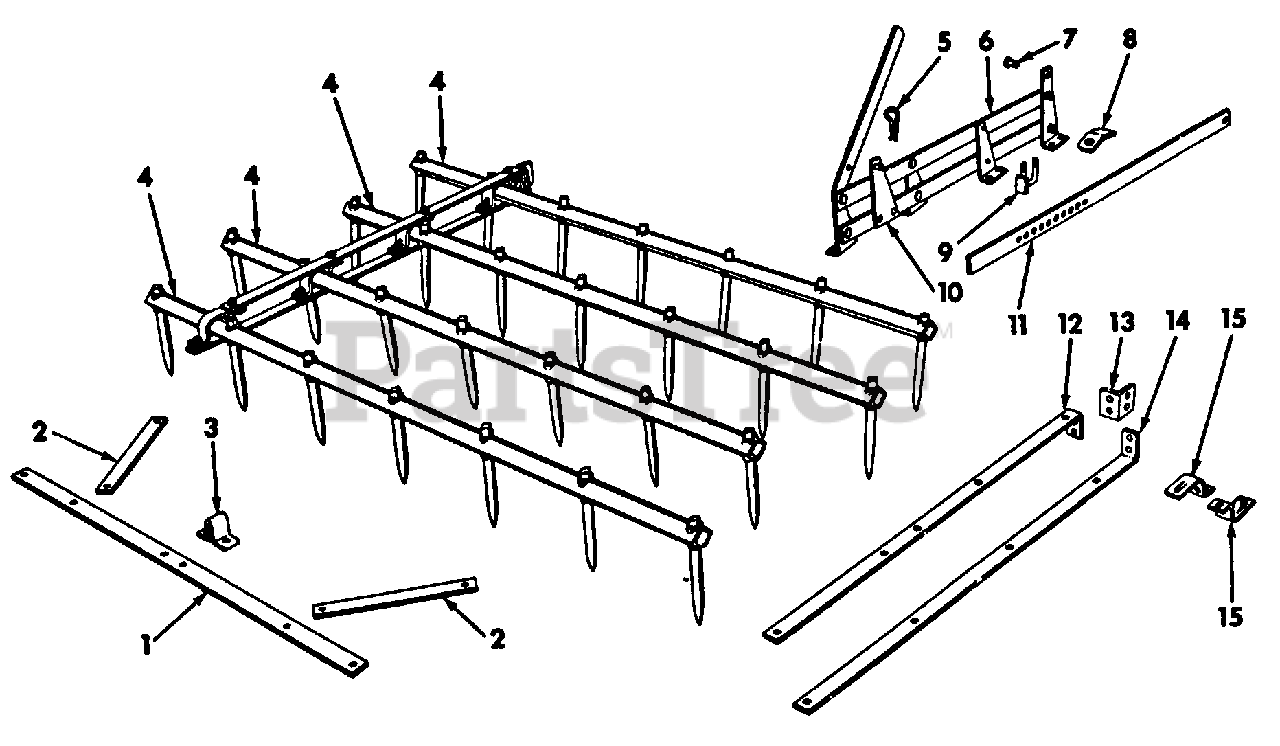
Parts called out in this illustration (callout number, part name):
1	Brace, Cross
2	Brace, Diagonal
3	Guide, Cross Brace
4	Bar Assembly, Tooth
5	Pin, Quick Attachable Cotter
6	Bar Assembly, Set
7	Pin, 1/2 X 7/8 C-Z Std-Hd Dld
8	Spacer, Set Bar Standard
9	U-Bolt Assembly
10	Bracket Assy, Quadrant
12	Frame Side, Upper
13	Angle, Draw
14	Frame Side, Lower
15	Bearing, Tooth Bar
